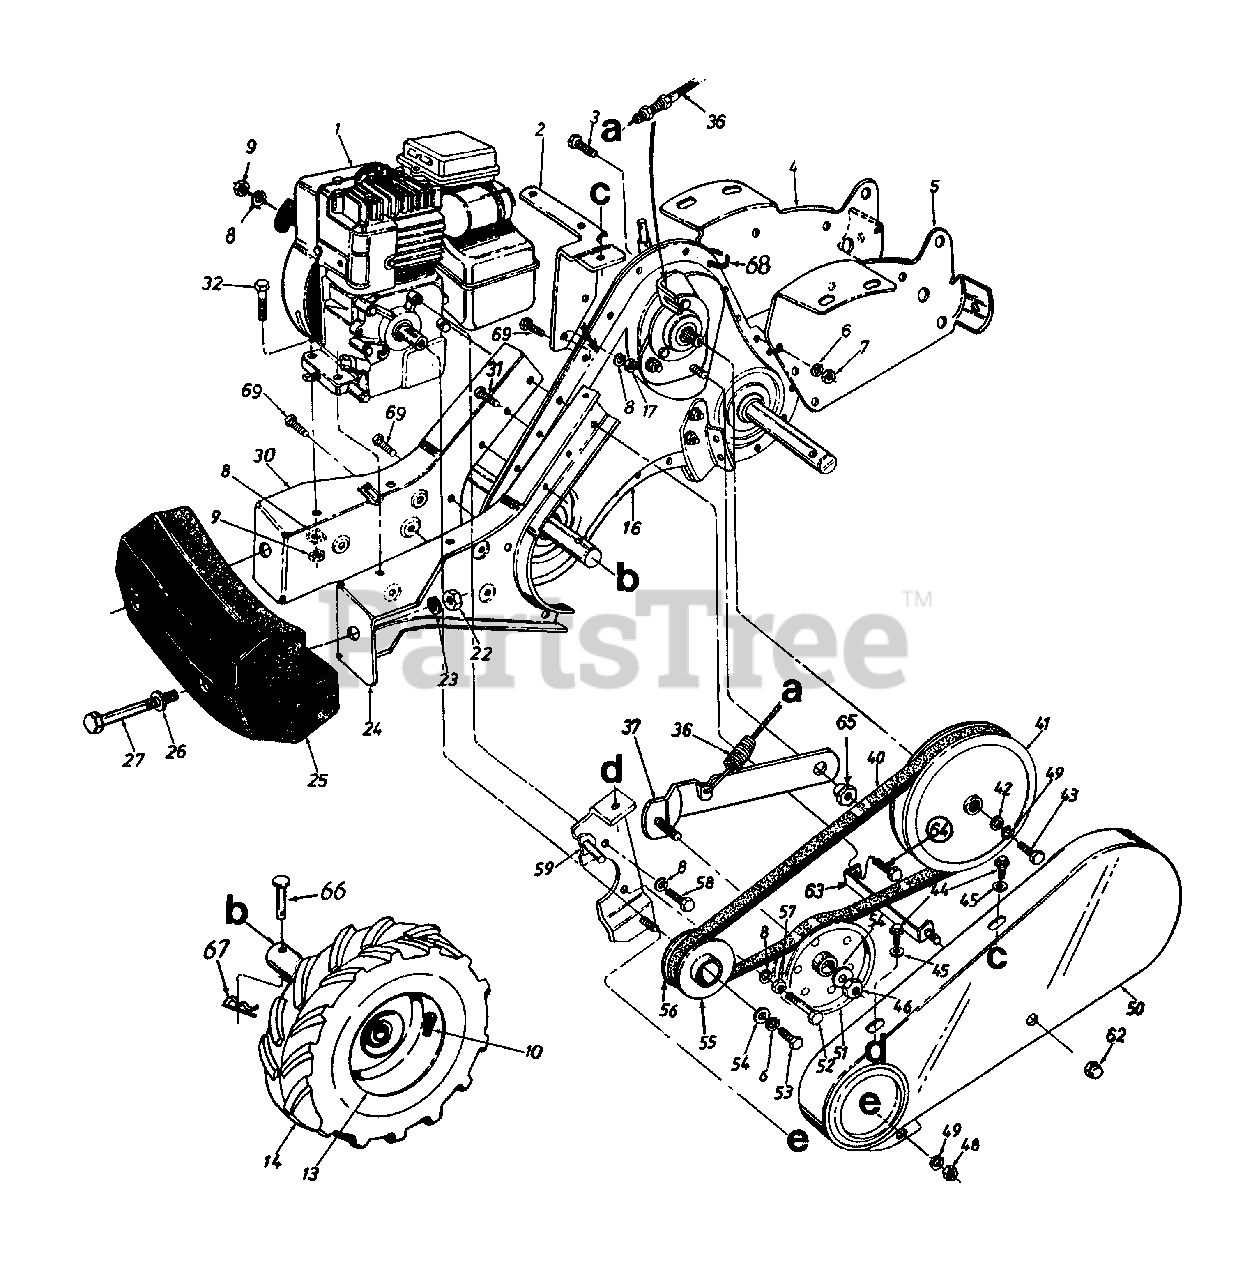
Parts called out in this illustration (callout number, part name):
1	Engine
7	Hex Nut 3/8-16 Thd.
8	L-Wash. 5/16" I.D.
9	Hex Nut 5/16-18" Thd.
10	Air Valve
16	Gear Case Ass'y. Comp.
17	Hex Nut 5/16-18 Thd.
22	Hex Nut 1/2-13 Thd.
23	L-Wash. 1/2" I.D.
26	Fl-Wash. .510" I.D. x 1.0"
27	Hex Bolt 1/2-13 x 5.00" Lg.
32	Hex Bolt 5/16-18 x 1.50"
36	Clutch Control Cable 46" Lg.
37	Idler Bracket Ass'y.
40	"V"-Belt
41	Fl-Pulley 8" O.D.
42	Fl-Wash. 1/4" I.D. x .93" O.D.
43	Hex Bolt 1/4-28 x .75" Lg.
44	Hex Wash. Hd. S-Tap Scr. 1/4-20 x .50" Lg.
45	Fl-Wash. .281" I.D. x .625"
46	Hex Cent. L-Nut 3/8-24 Thd.
48	Hex Nut 1/4-20 Thd.
49	L-Wash. 1/4" I.D.
51	Fl-Idler w/Flanges 3.75" O.D.
52	Hex Bolt 5/16-24 x 1.75"
53	Hex Bolt 3/8-24 x 1.00" Lg.
54	Fl-Wash. 3/8" I.D. x 1.00"
55	Outer Engine Pulley Half
56	Inner Engine Pulley Half
57	Hex Nut 5/16-24 Thd.
58	Hex Bolt 5/16-24 x .62" Lg.
63	Belt Cover Brkt. Ass'y.
64	Hex Bolt 5/16-18 x 1" Lg. (Gr. 5)
65	Shld. Nut
66	Clevis Pin
67	Hairpin Clip
68	Cable Tie-Self Clinching
69	Screw 5/16-18 x 1"
